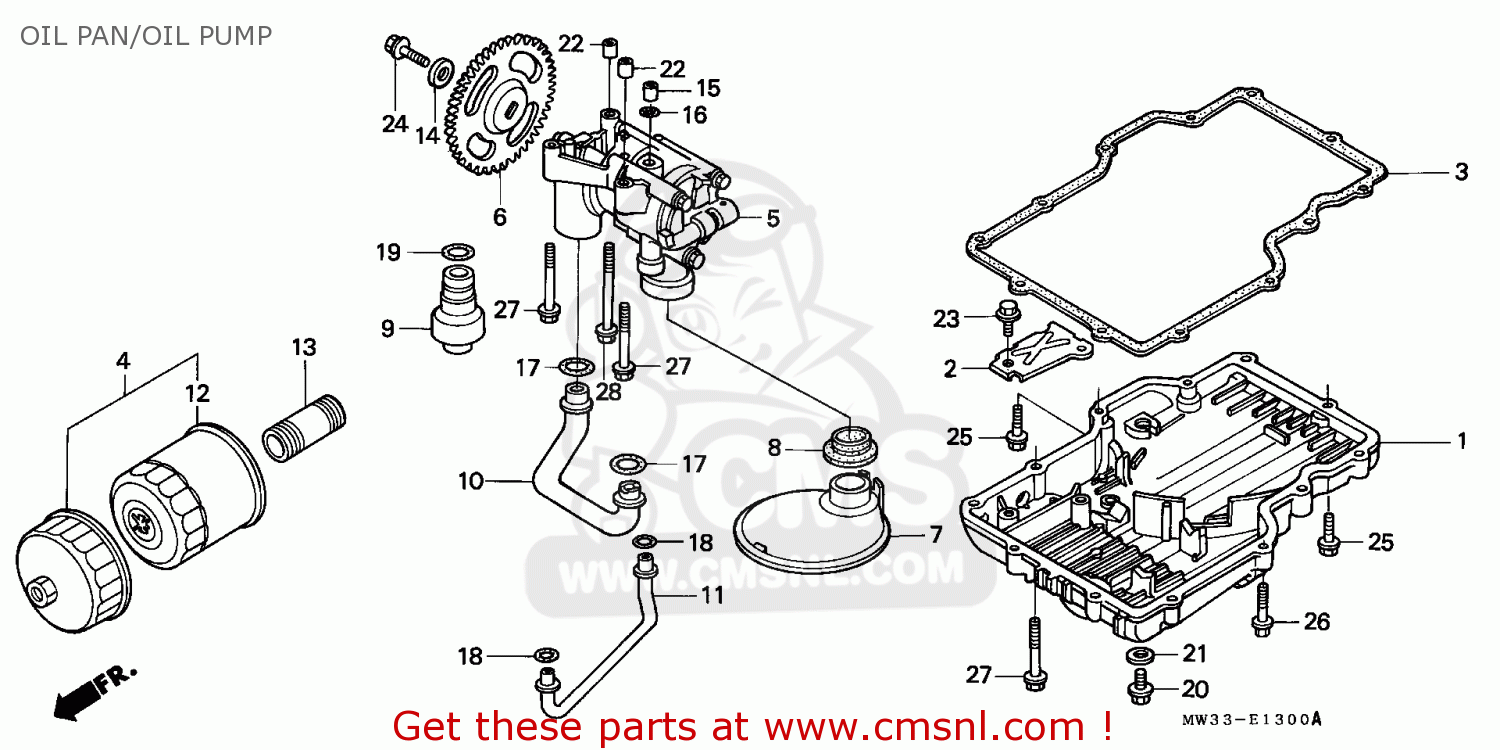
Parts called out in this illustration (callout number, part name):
1	PAN,OIL
2	PLATE,BAFFLE
3	GASKET,OIL PAN (NAS)
4	FILTER SET,OIL
5	PUMP ASSY.,OIL
6	GEAR OIL/P DIRVEN
7	OIL STRAINER
8	PKG OIL STRAINER (NAS)
9	VALVE ASSY,RELIEF
10	PIPE,OIL PATH
11	PIPE B,OIL PATH
12	CARTRIDGE,OIL FIL
13	BOSS, OIL FILTER
14	WASHER, DRUM STOP
15	PIN,O-RING GUIDE
16	O RING,7.8X1.9
17	O-RING,14.6X3.6
18	O RING,9.8X2.8
19	O-RING,14.8X2.4
20	BOLT DRAIN 12MM
23	BOLT,FLANGE,6X12
24	BOLT,FLANGE,6X16
25	BOLT,FLANGE,6X28
26	BOLT,FLANGE 6X32
27	BOLT,FLANGE,6X40
28	BOLT,FLANGE 6X75
